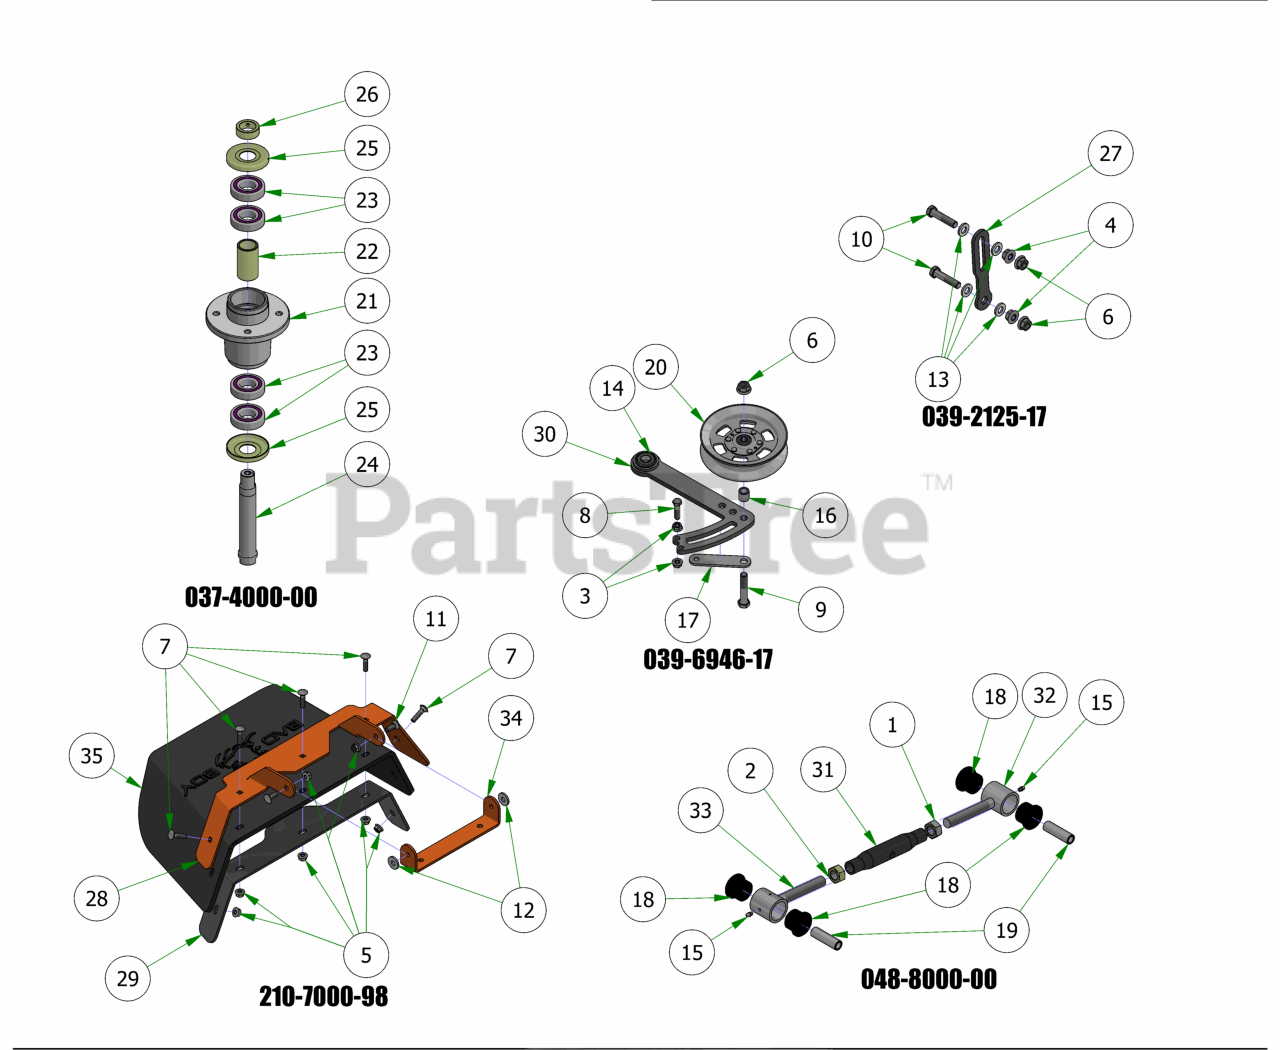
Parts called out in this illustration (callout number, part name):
1	Hex Nut M20-2.5
2	Hex Nut M20-2.5 Left Hand Threads Gold Plated
3	3/8-16 HEX SERRATED FLANGE NUT HARD/ZINC
4	1/2-13 HEX SERRATED FLANGE NUT HARD/ZINC
5	5/16-18 NYLON INSERT FLANGE LOCKNUT ZINC
6	1/2-13 NYLON INSERT FLANGE LOCKNUT ZINC
7	5/16-18 X 1-1/4 CARRIAGE BOLT ZINC
8	3/8-16 X 1-1/2 HEX CAP SCREW (GR.5) ZINC
9	1/2-13 X 2-3/4 HEX CAP SCREW (GR.5) ZINC
10	1/2-13 X 2-1/4 HEX CAP SCREW (GR.5) ZINC
11	5/16-18 X 7/8 CARRIAGE BOLT ZINC
12	.360 ID X .983 OD X .120 THICK FLAT WASHER NYLON
13	.505 ID X 1.000 OD X .125 THICK FLAT WASHER NYLON
14	Ball Bearing w/Retainer, 99502H-NR, .625 Bore x 1.375 OD x .4375 Width
15	1/4-28 Grease Fitting
16	.51 ID X .75 OD X .75 LGTH SOLID SPACER ZINC
17	Belt Tensioner Retainer Plate
18	Polyeurethane Bushing
20	5" Idler Pully
21	4000 Series Spindle Housing
22	4000 Series Spindle Spacer
23	Bearing - 6206
24	Spindle Shaft
25	Spindle Dust Cap
26	Locking Collar w/ 1/4"-20 Set Screw
27	Deck Hanger
28	2019 Upper Chute Bracket
29	2019 Lower Chute Bracket
30	2019 Deck Belt Tensioner
31	2024 Turnbuckle Body
32	Turnbuckle End Right-Handed Thread
33	Turnbuckle End Left-Handed Thread
34	2019 Chute Hanger
35	2019 Belted Chute with Logo
